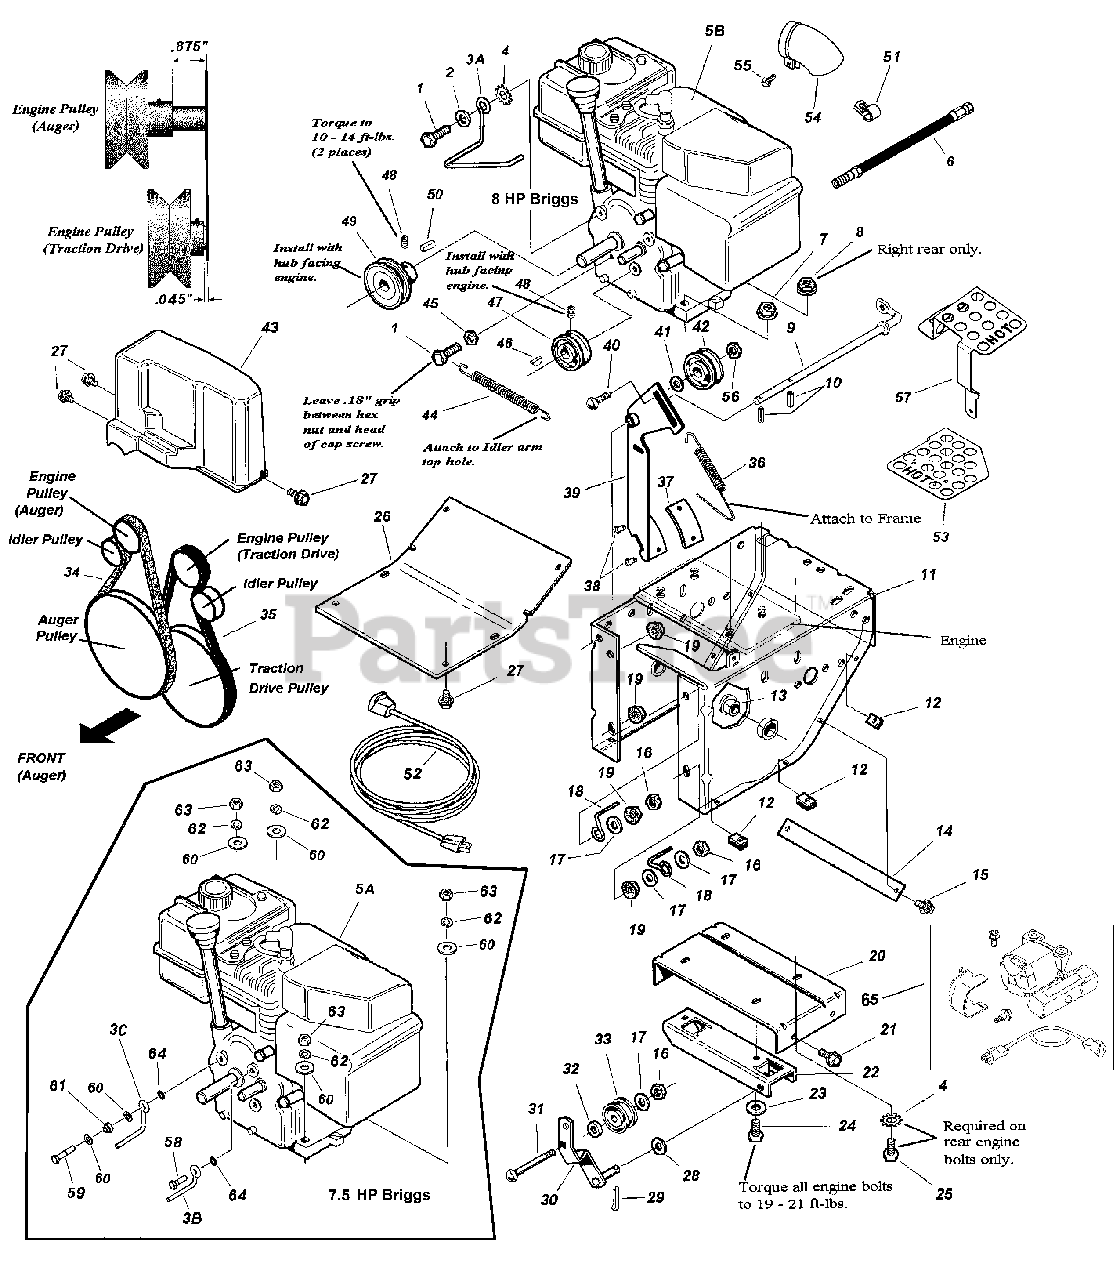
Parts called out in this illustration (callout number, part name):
1	SCREW, 5/16-24 x 1-1/4" Hex Head Cap, GR 5
2	WASHER, 5/16" Flat
3A	BELT STOP, Wire
3B	BELT GUIDE, LH, Traction Drive Belt
3C	BELT GUIDE, RH, Traction Drive Belt
4	LOCKWASHER, 5/16" Exterior Tooth
6	HOSE, Oil Drain
7	NUT, 5/16-18 Hex Flange Lock- small
8	NUT, 5/16-18 Hex Flange Lock
10	ROLL PIN, 3/16 x 3/4"
11	WELDMENT, Intermediate Frame- Orange
12	SPEED NUT, 1/4-20 U-Type
13	BUSHING, 1.00 long
14	SUPPORT, Tie Bar
15	SCREW, #10-24 x 1/2" Hex Washer Self-Tap
16	JAM NUT, 3/8-16 Hex Center Lock
17	WASHER, 3/8" SAE Flat
18	ROD, Belt Guide
19	NUT, 3/8-16 Hex Nyloc Heavy Thin
20	SUPPORT, Frame
21	SCREW, 5/16-18 x 1/2" Hex Washer Self-Tap
22	SUPPORT, Pivot
23	WASHER, 5/16" Flat
24	SCREW, 5/16-18 x 1-3/4" Hex Head Cap, GR 5
25	SCREW, 5/16-18 x 1-3/4" Hex Head Cap, GR 5
26	COVER, Bottom- Orange
27	SCREW, 1/4-20 x 5/8" Hex Washer Self-Tap
28	WASHER, 7/16" Flat
29	COTTER PIN, 1/8 x 3/4"
30	WELDMENT, Idler Arm
31	BOLT, 3/8-16 x 1-1/4" Short Square Neck Carriage, GR 5
32	SPACER, .377 ID x .75 OD x .312 Long
33	PULLEY, Idler
34	BELT, V Groove, 4L Sect.; 36.00" nom. effective length
35	V-BELT, 3L, 31.64 effective length
36	SPRING, Extension
38	RIVET, Blind
39	ASSEMBLY, Idler Arm w/Brake Pad
40	BOLT, 3/8-16 x 1-3/4" Short Square Neck Carriage, GR 5
41	WASHER, 3/8" Flat (.41 ID x 1.00 OD x .13 Thick)
42	PULLEY, Idler
43	COVER, Belt
44	SPRING, Extension, .562 O.D. x 4.250 Long
45	JAM NUT, 5/16-24 Hex
46	KEY, Hi Pro .125 x .625 HP 504 SAE1035
47	PULLEY, V Groove
48	SET SCREW, 5/16-18 x 5/16" Hex Recess, Cup Point
49	PULLEY, 2.75 OD
50	KEY, 3/16 Square x 1"
51	HARNESS CLIP
52	CORD, Electric Start
53	GUARD, Muffler
54	MUFFLER, Deflector- B&S
55	HEX SCREW, Thread Rolling M4 x 0.7
56	NUT, 3/8-16 Hex Flange Lock Two Way
57	HEAT SHIELD, 7.5HP B&S Powerbuilt Muffler
58	SCREW, 5/16-24 x 1" Hex Head Cap, GR 5
59	SCREW, 5/16-24 x 1-1/2" Hex Head Cap, GR 5
60	WASHER, 5/16" Flat
61	BUSHING, Differential Link
62	WASHER, 5/16" Split Lock
63	NUT, 5/16-18 Hex, GR 5 or B
64	WASHER, 5/16" Internal Tooth Lock
65	KIT, Electric Start, 320 volt
